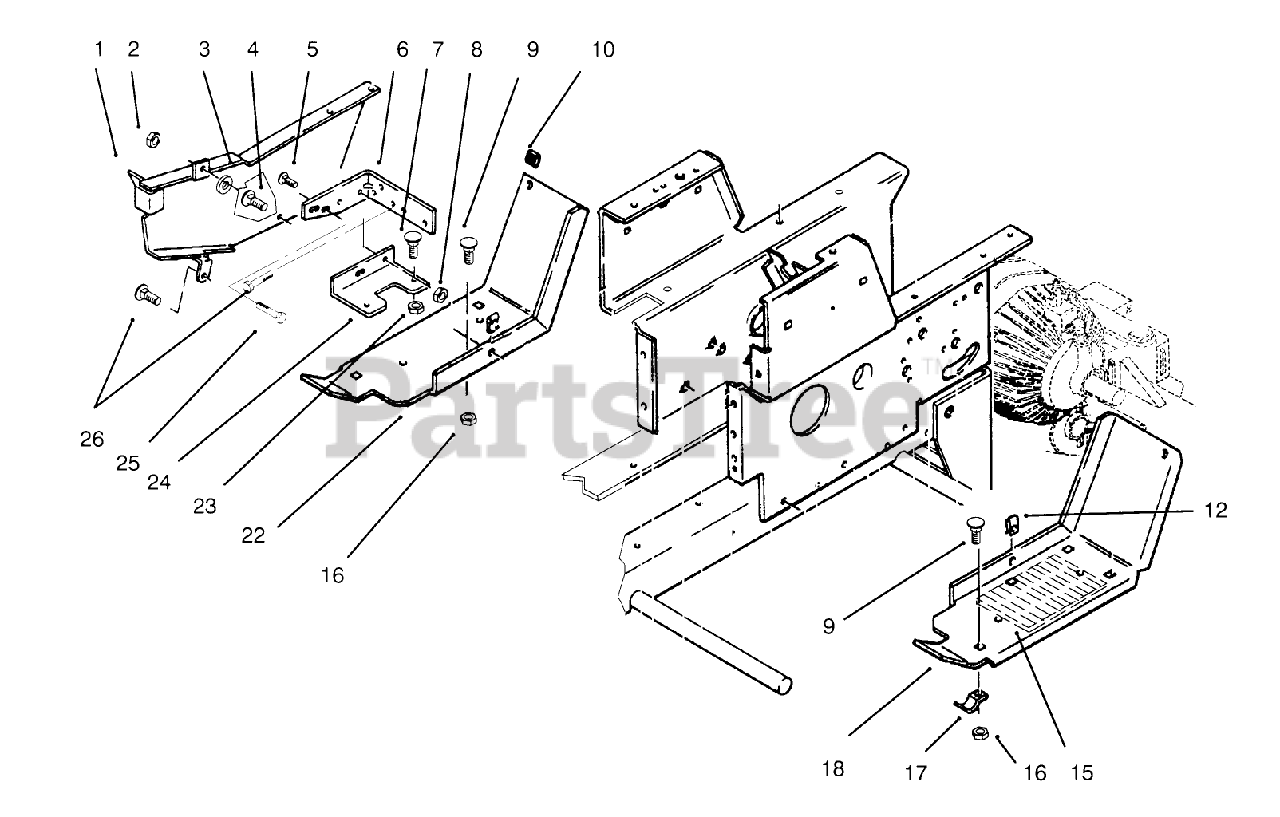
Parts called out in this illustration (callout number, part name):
1	GUARD - BELT WA *R
2	NUT-LOCK, NI
5	SCREW-HH
6	BRACKET-BELT*B
8	NUT-LOCK, NI
9	BOLT-CARR
10	BUMPER
15	PAD FOOTREST
16	NUT-LOCK, NI
17	BRACKET
18	FOOTREST LH *R
24	BRKT-FUS HLDER*B
25	BOLT-CARR
26	SCREW
